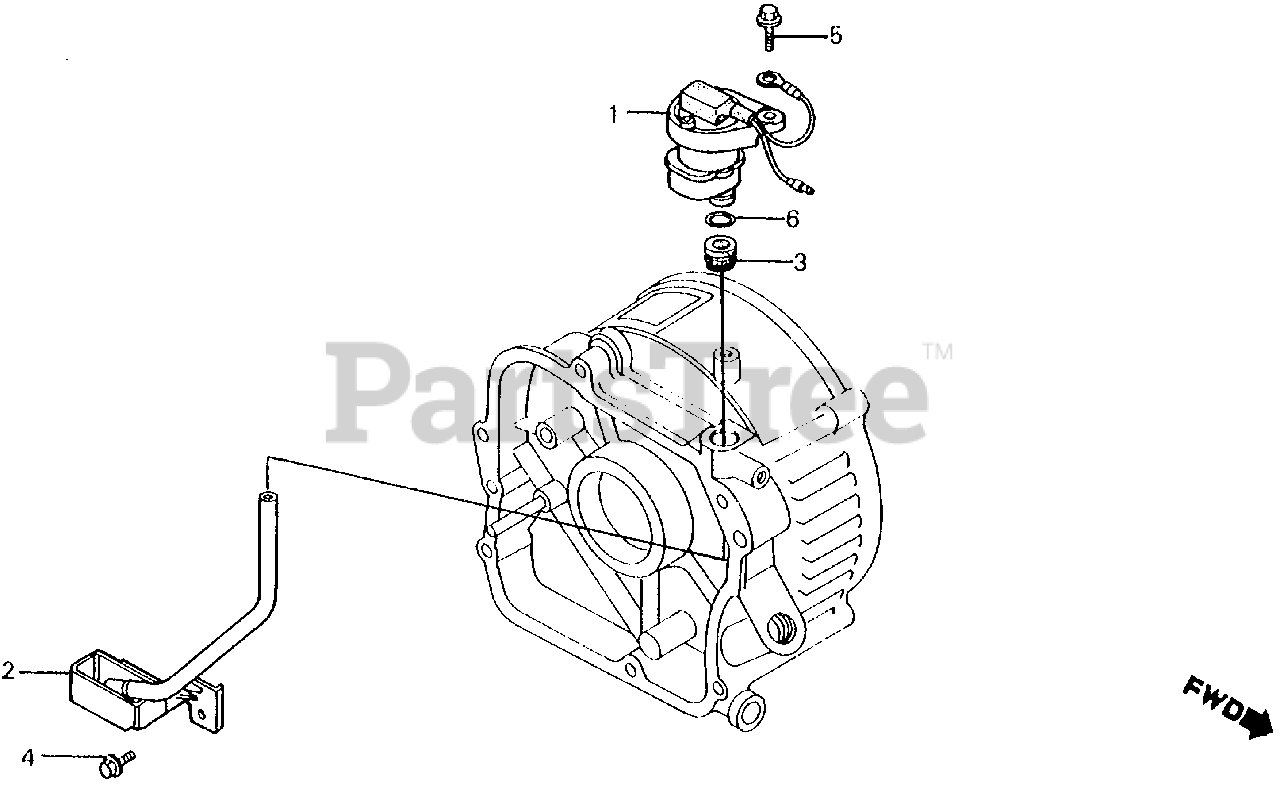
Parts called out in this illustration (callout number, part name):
1	SWITCH ASSY., UNIT (NOT AVAILABLE)
2	CUP, OIL (NOT AVAILABLE)
3	PLUG, OIL ALERT SEAL
4	BOLT, FLANGE (5X10)
5	BOLT, FLANGE (5X16)
6	O-RING (11X2.0)
